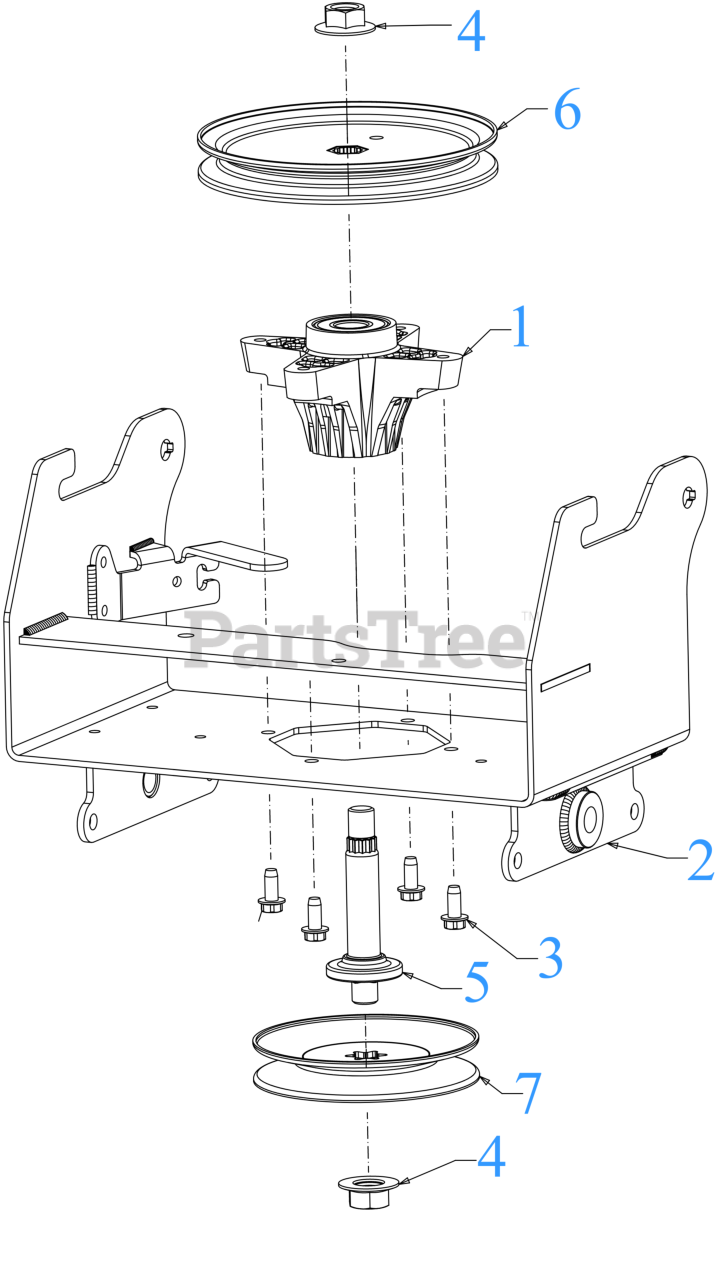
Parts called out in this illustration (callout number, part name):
1	SPINDLE HOUSING ASSEMBLY
2	SPINDLE MOUNTING BRACKET (POWDER BLACK)
3	SCREW 5/16-18 x .750
5	BLADE SPINDLE SHAFT 4.125 LG
6	V-PULLEY 7.25 DIA
7	V-PULLEY 5.57 DIA
